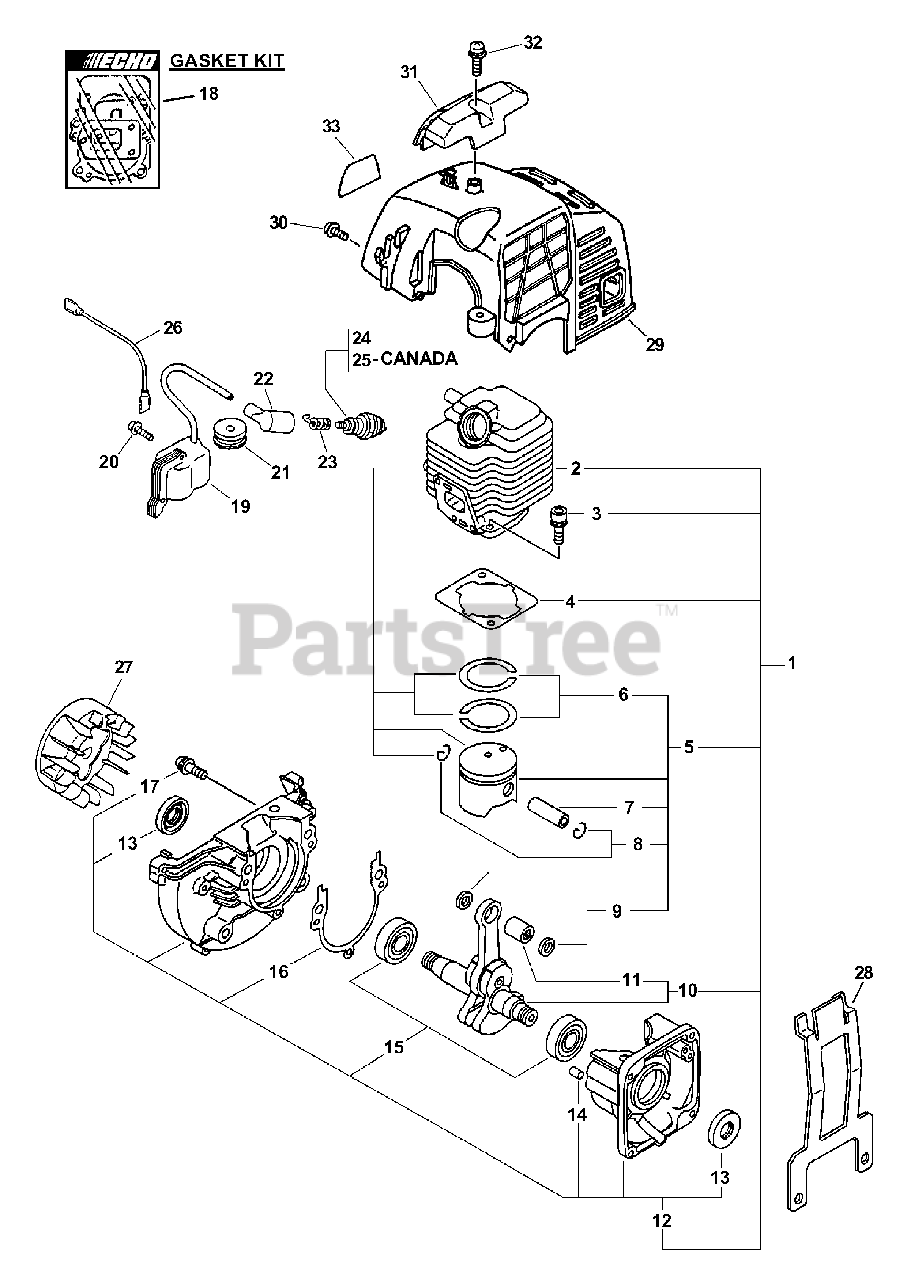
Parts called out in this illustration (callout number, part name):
1	SHORT BLOCK -- SB1027
2	CYLINDER KIT
3	SCREW - 5X22
4	GASKET, CYLINDER
5	PISTON KIT
6	RING, PISTON
7	PIN, PISTON
8	RING, RETAINING
9	SPACER, PISTON
10	CRANKSHAFT ASSY
11	BEARING, NEEDLE - 8
12	CRANKCASE KIT
13	SEAL, OIL
14	PIN - LOCATING
15	BEARING, BALL - 6201
16	GASKET, CRANKCASE
17	SCREW - 5X28
18	GASKET KIT
19	COIL, IGNITION
20	SCREW - 4X22
21	GROMMET
22	CAP, SPARK PLUG
23	TERMINAL, SPARK PLUG CAP
24	SPARK PLUG -- BPM-7Y
25	SPARK PLUG -- BPMR-7A
26	LEAD - IGNITION
27	FLYWHEEL
28	GUARD, ENGINE
29	COVER, ENGINE - ORANGE
30	SCREW - 4X12
31	GUARD, TOP - BLACK
32	SCREW - 5X16 -- TAPPING
33	LABEL - MODEL PPT-2400 T1E
